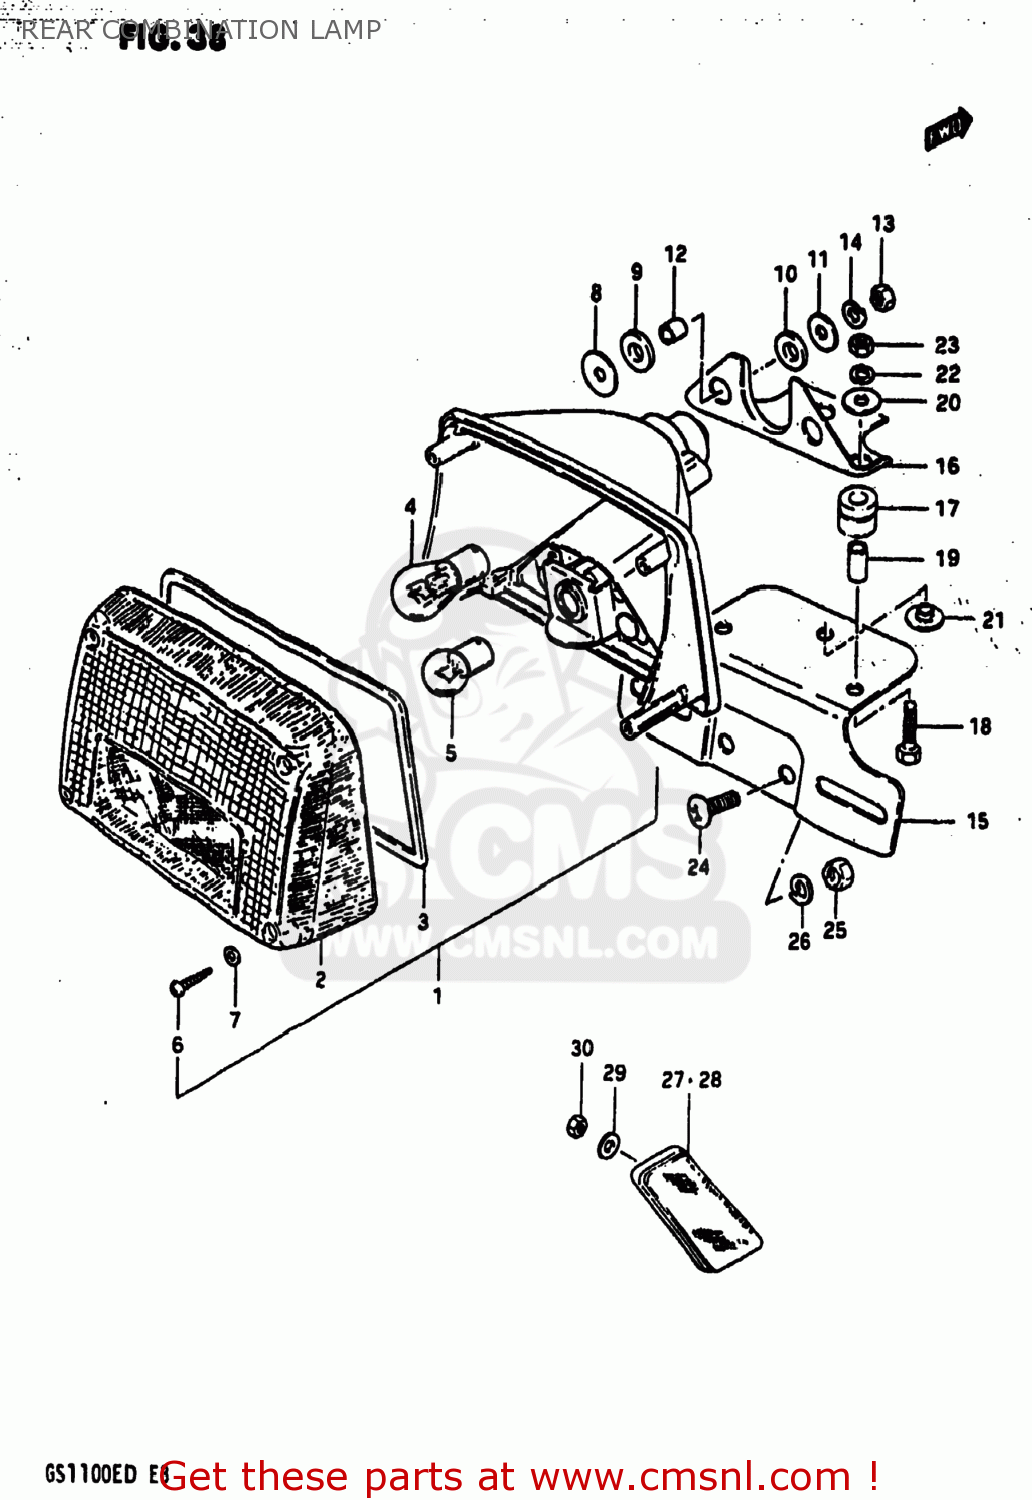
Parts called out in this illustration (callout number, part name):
1	LAMP ASSEMBLY,REAR COMBINATION
2	LENS
3	GASKET (NAS)
4	BULB(12V23W)
5	BULB
6	SCREW,REAR COMBINATION LAMP
7	GASKET (NAS)
8	WASHER
9	CUSHION
10	CUSHION
11	WASHER(6,5X22X1.6)
12	SPACER(6.1X9X7.5)
13	NUT
14	LOCK WASHER
15	PLATE,REAR LICENSE
16	BRACKET,LICENSE PLATE
17	CUSHION, BRACKET
18	BOLT
19	SPACER (6.4X9X15.5)
20	WASHER
21	WASHER
22	LOCK WASHER
23	NUT
24	SCREW
25	NUT
26	LOCK WASHER
27	REFLECTOR,REFLEX,RIGHT
28	REFLECTOR,REFLEX,LEFT
29	WASHER(5.2X16X1)
30	NUT
